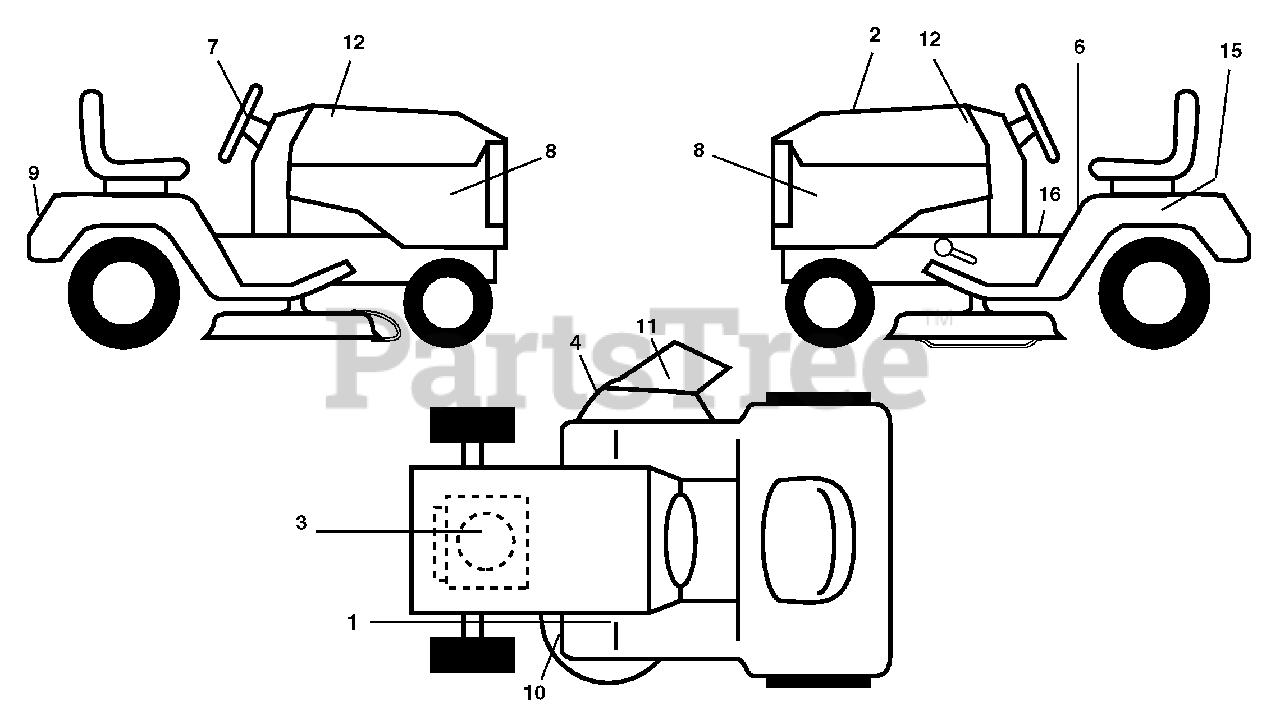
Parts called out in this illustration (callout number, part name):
1	Decal, Clutch/Brake Eng/Fr
2	Decal, Replacement
3	Decal, Engine HP
4	Decal Warning
6	Decal, Fender Danger English
7	Decal Ins Str Wh
8	Decal, Side Panel
9	Decal, Fender
10	Decal, V-Belt Sch.
11	Decal, Deck "B" "42"
12	Decal, Hood
15	Decal, Caution, Battery
16	Decal, Oper Sdl P/L Gear Dr Eng
